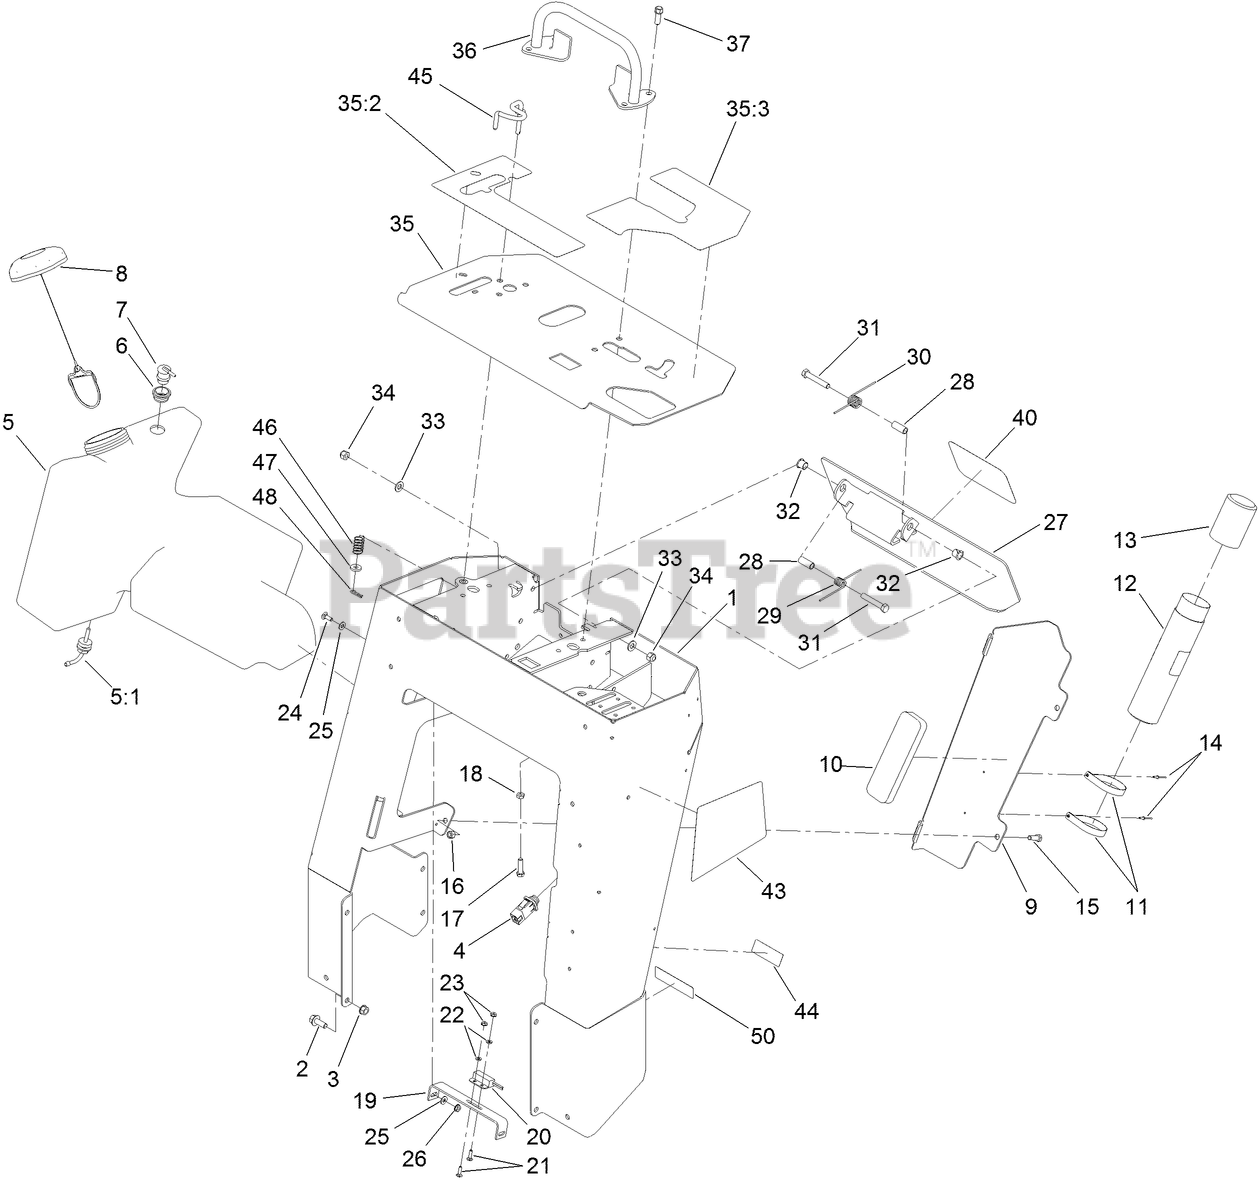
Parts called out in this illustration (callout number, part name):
2	SCREW-HHF
3	NUT-FLANGE
4	SWITCH-PLUNGER
5	TANK-FUEL
5:1	FITTING-FUEL, BULKHEAD
6	GROMMET
7	VALVE-ROLLOVER
8	CAP-FUEL, RATCHETING
9	BRACKET-COVER, TANK
10	PAD-FOAM
11	CLAMP-R
12	TUBE-MANUAL
13	CAP-HOUSING
14	RIVET-POP
15	SCREW-HH
16	NUT-LOCK, NI
17	SCREW-HH
18	NUT-JAM
19	PLATE-SWITCH
20	SWITCH-PROXIMITY
21	SCREW-CARR
22	WASHER-FLAT
23	NUT-KEPS
24	BOLT-CARR
25	WASHER-FLAT
26	NUT-KEPS
27	PLATE-REVERSE
28	SPACER-SPRING
29	SPRING-TORSION, LH
30	SPRING-TORSION, RH
31	SCREW-HH
32	BUSHING-NYLINER
33	WASHER-FLAT
34	NUT-LOCK, NI
35	PANEL-CONTROL
35:2	DECAL-CONSOLE, RH
35:3	DECAL-CONSOLE, LH
36	BAR-REFERENCE
37	SCREW-TAPTITE
43	DECAL-SIDE, LH
44	DECAL-INFO
45	ROD-INTERLOCK
46	SPRING-CONTROL
47	WASHER-FLAT
48	PIN-COTTER
50	DECAL-ARRESTER, SPARK
